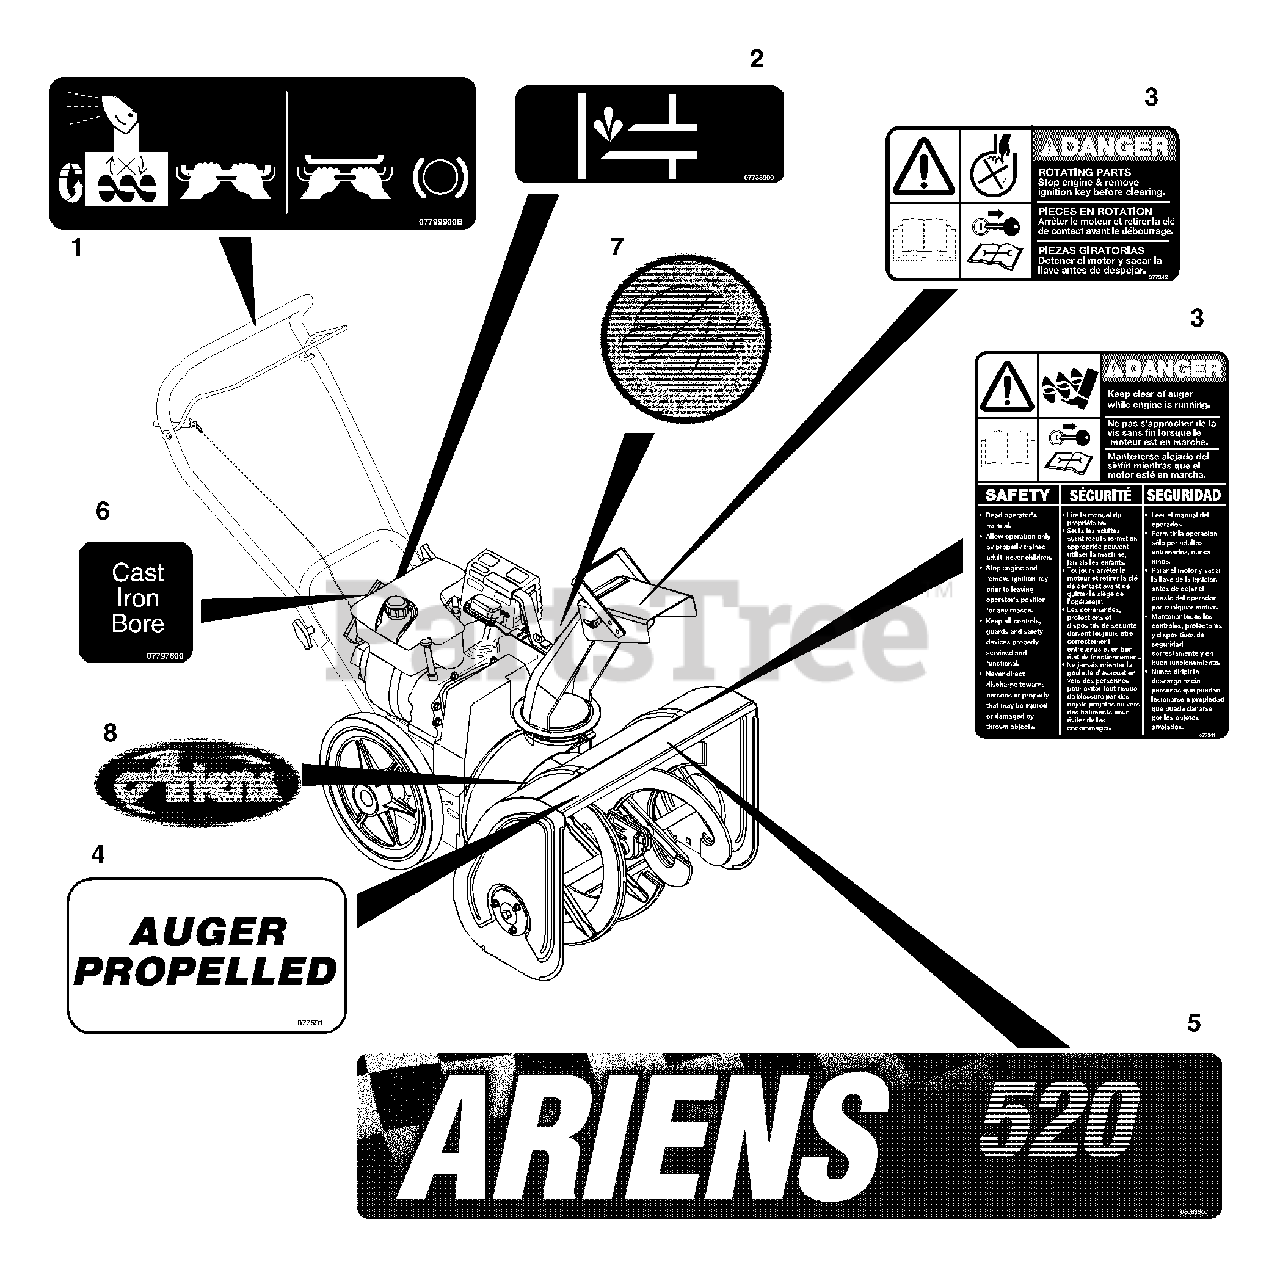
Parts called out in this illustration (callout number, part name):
1	HANDLEBAR DECAL
2	DECAL, PRIMER "TECUMSEH'S"
3	DECAL SET - DANGER
4	DECAL AUGER PROPELLED
5	DECAL - 520 BLOWER HOUSING
6	DECAL - CAST IRON BORE
7	DECAL, A+
8	DECAL, "ARIENS" JEWEL
